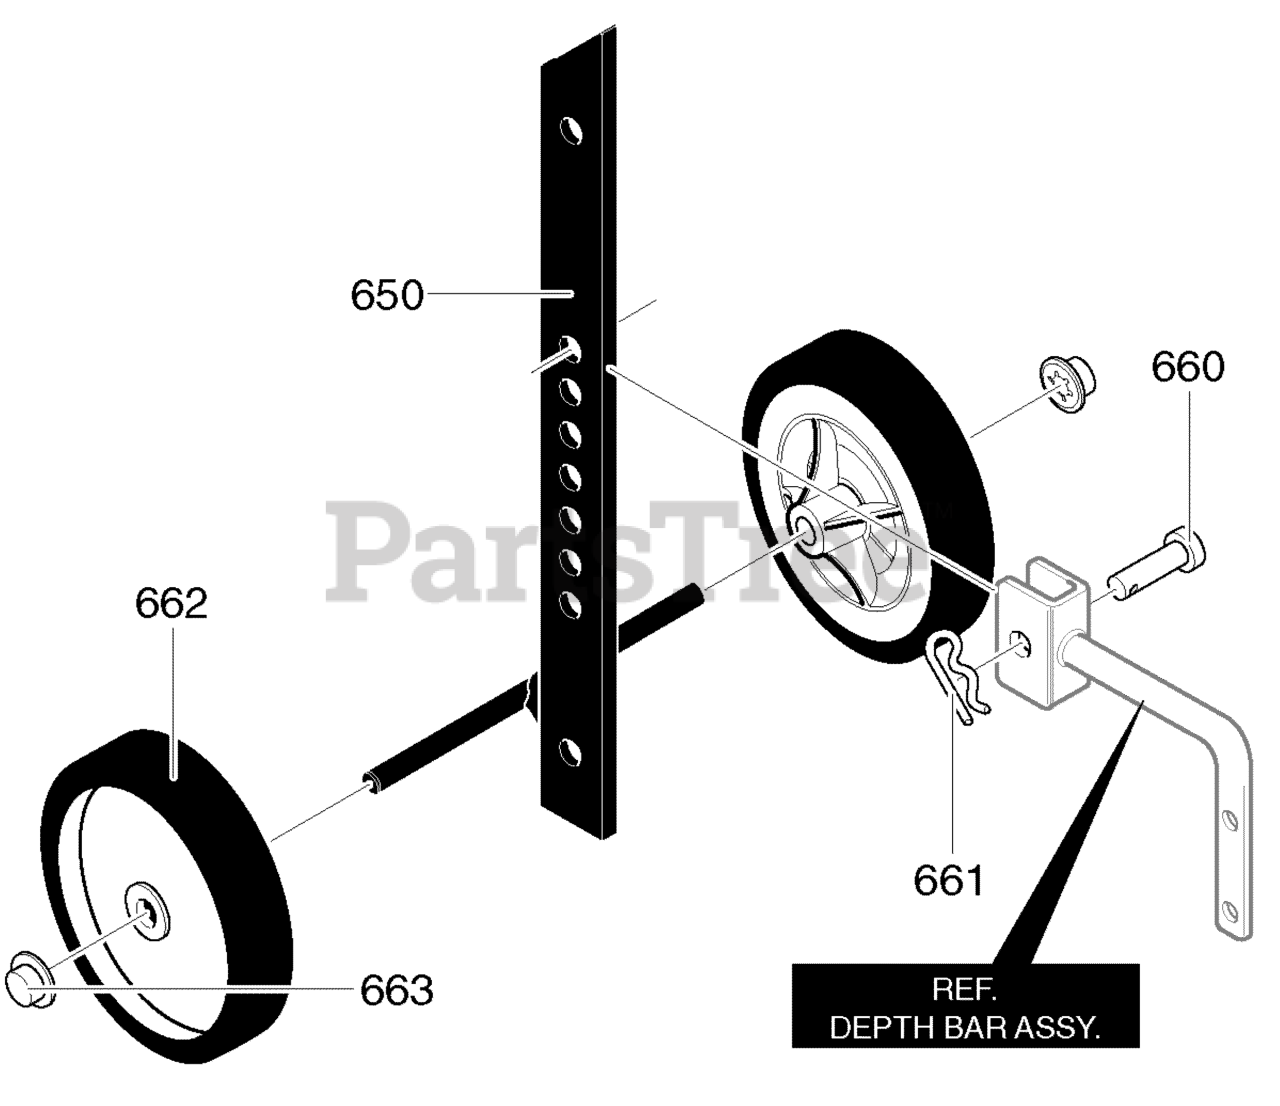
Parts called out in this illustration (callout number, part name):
650	Wheel Support Assy.
660	Clevis Pin
661	Hair Pin
662	Tire & Rim
663	Push On Nut
